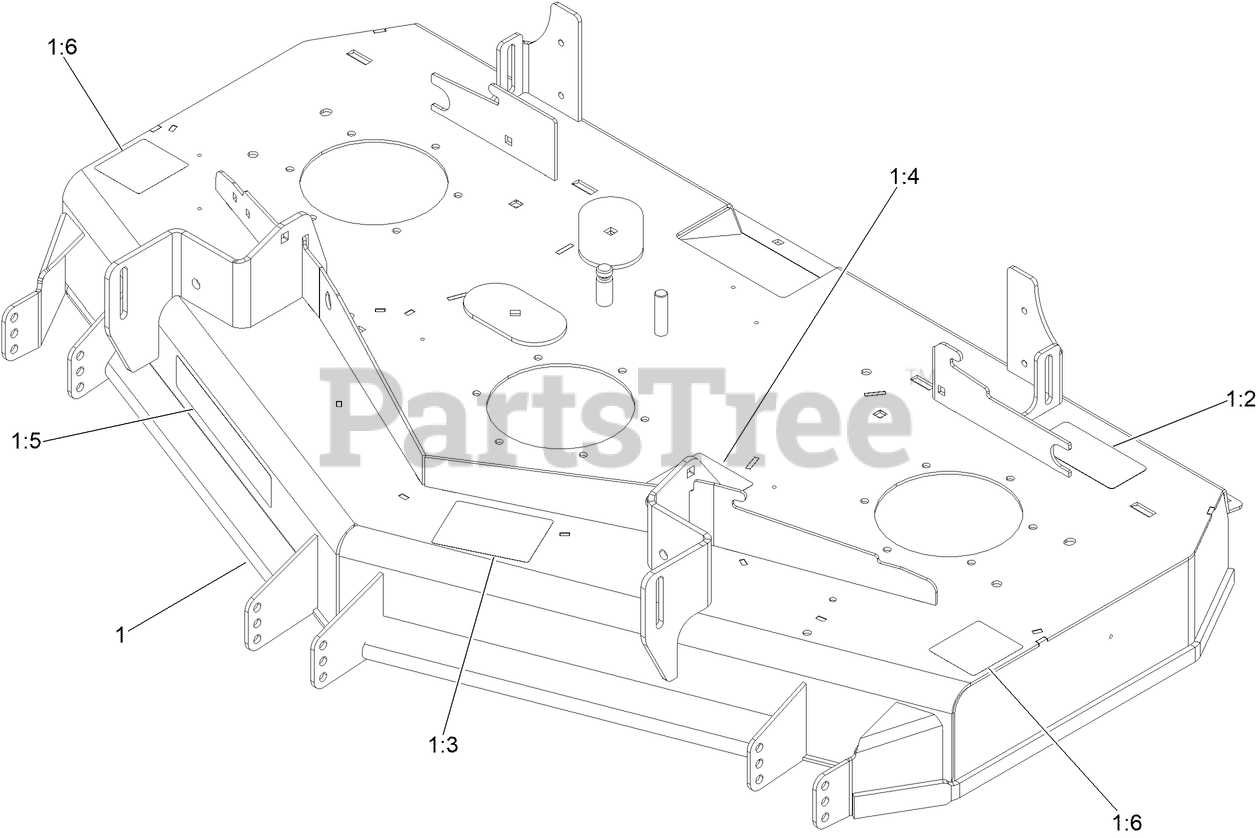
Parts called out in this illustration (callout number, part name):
1	DECK ASM
1:2	DECAL-TORQUE, BLADE BOLT
1:3	DECAL-SCALP, ANTI
1:4	DECAL-ROUTING, BELT
1:6	DECAL-DANGER, THROWN OBJECT
